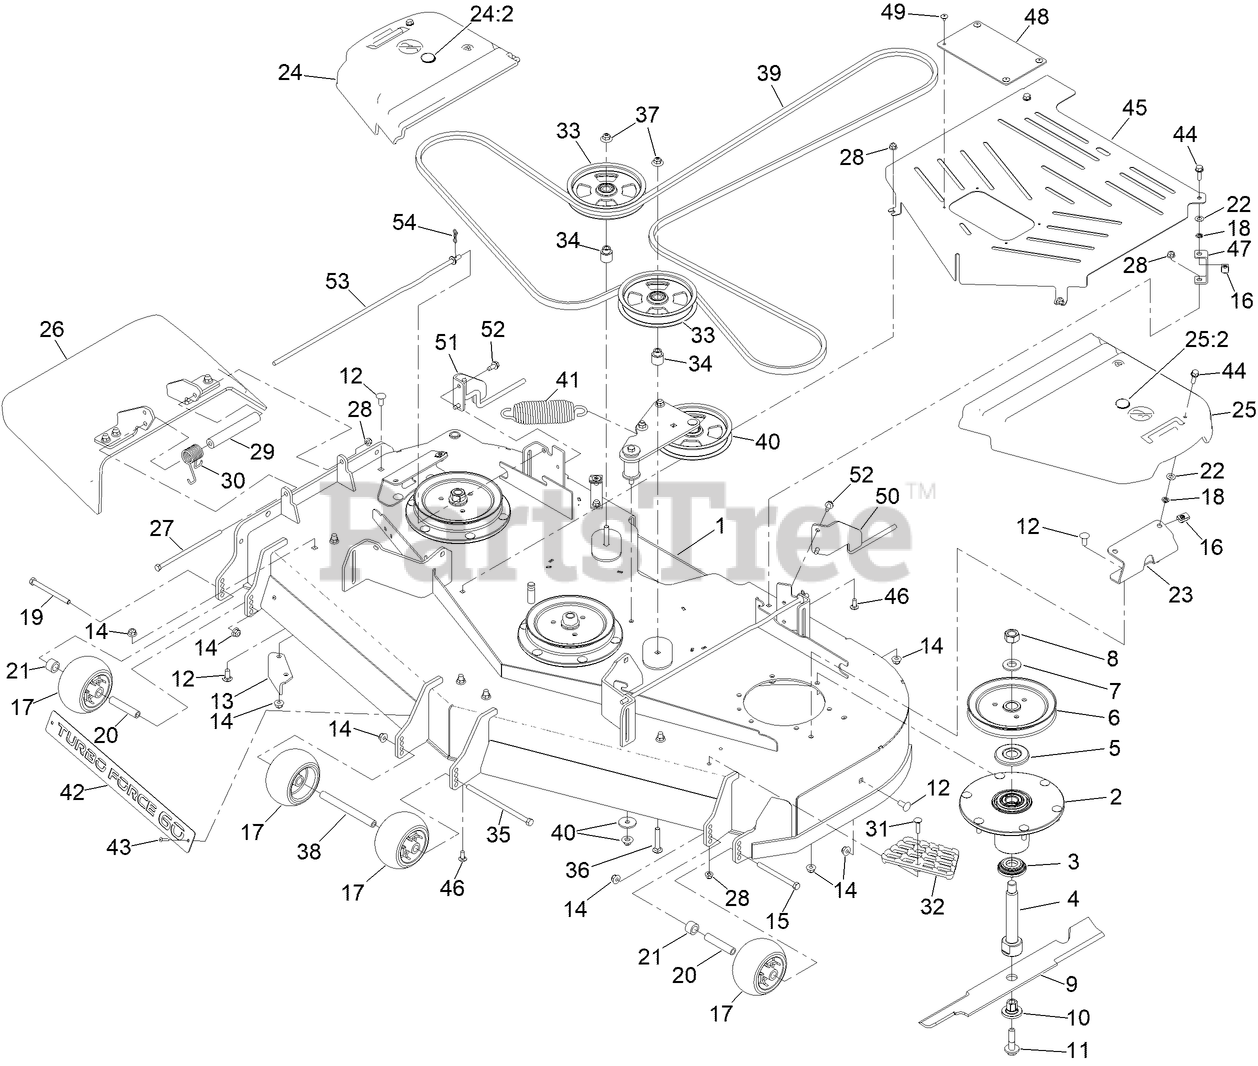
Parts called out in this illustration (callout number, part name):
1	DECK DECAL ASM
2	SPINDLE ASM
3	GUARD-BOTTOM
4	SHAFT-SPINDLE
5	GUARD-BEARING, TOP
6	SHEAVE-DRIVE, BLADE
7	WASHER
8	NUT-HEX
10	BUSHING-HEX
11	SCREW-SEMS
12	SCREW-CARR
13	BAFFLE-DISCHARGE
14	NUT-HF, NI
15	SCREW-HH
16	NUT-U
17	ROLLER-SCALP, ANTI
18	NUT-PUSH
19	SCREW-HH
20	TUBE-SHAFTING
21	TUBE-SPACER
22	WASHER-THRUST
23	BRACKET-COVER, BELT
24	RH BELT COVER ASM
24:2	PLUG-PLASTIC
25	LH BELT COVER ASM
25:2	PLUG-PLASTIC
26	RUBBER DEFLECTOR ASM
27	SCREW-HH
28	NUT-HF, NI
29	SPACER
30	SPRING-TORSION
31	SCREW-CARR
32	STEP-DECK
33	PULLEY-IDLER, FLAT
34	BUSHING, IDLER
35	SCREW-HH
36	SCREW-CARR
37	NUT-FLANGE, NI
38	SPACER-WHEEL
39	BELT-V
40	IDLER ARM ASM
41	SPRING-EXTENSION
42	PLATE-TURBO FORCE [BLACK]
43	RIVET-TRIFOLD
44	SCREW-HHF
45	GUARD-CENTER BELT 60
46	SCREW-CARR
47	BRACKET-GUARD
48	SHIELD-RUBBER
49	RIVET-POP
50	SUPPORT-LOWER LH
51	SUPPORT-LOWER RH
52	SCREW-HWHTF
53	ROD-SKIRT, LOWER
54	PIN-COTTER, LOCKING
